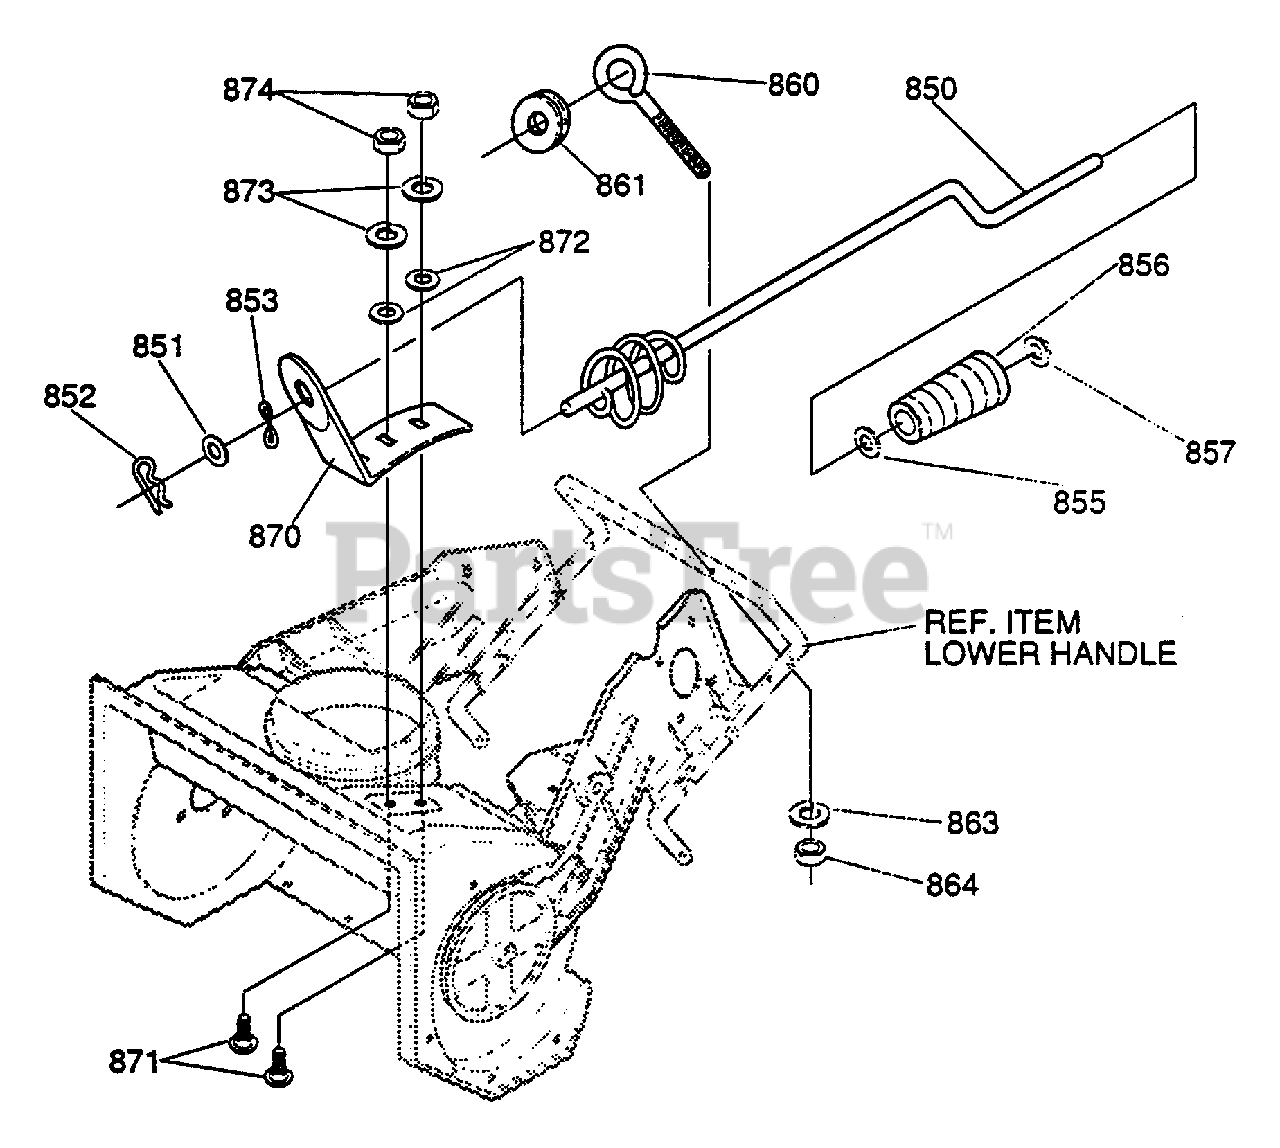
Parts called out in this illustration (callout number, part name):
850	ROD, ASSY UPR CHUTE CTRL
851	WASHER, FLAT
852	PIN, COTTER
853	WASHER, CURVED SPRING
855	WASHER, FLAT
856	KNOB, SLEEVE
857	CAP NUT, PUSH-ON
861	GROMMET, EYE BOLT
863	WASHER, REG SPTLK
864	NUT, 3/8-16
870	BRACKET, CHUTE ROTATE
871	BOLT, 5/16-18 X .63
872	WASHER, FLAT
873	WASHER, HVSPTLK
874	NUT, 5/16-18
